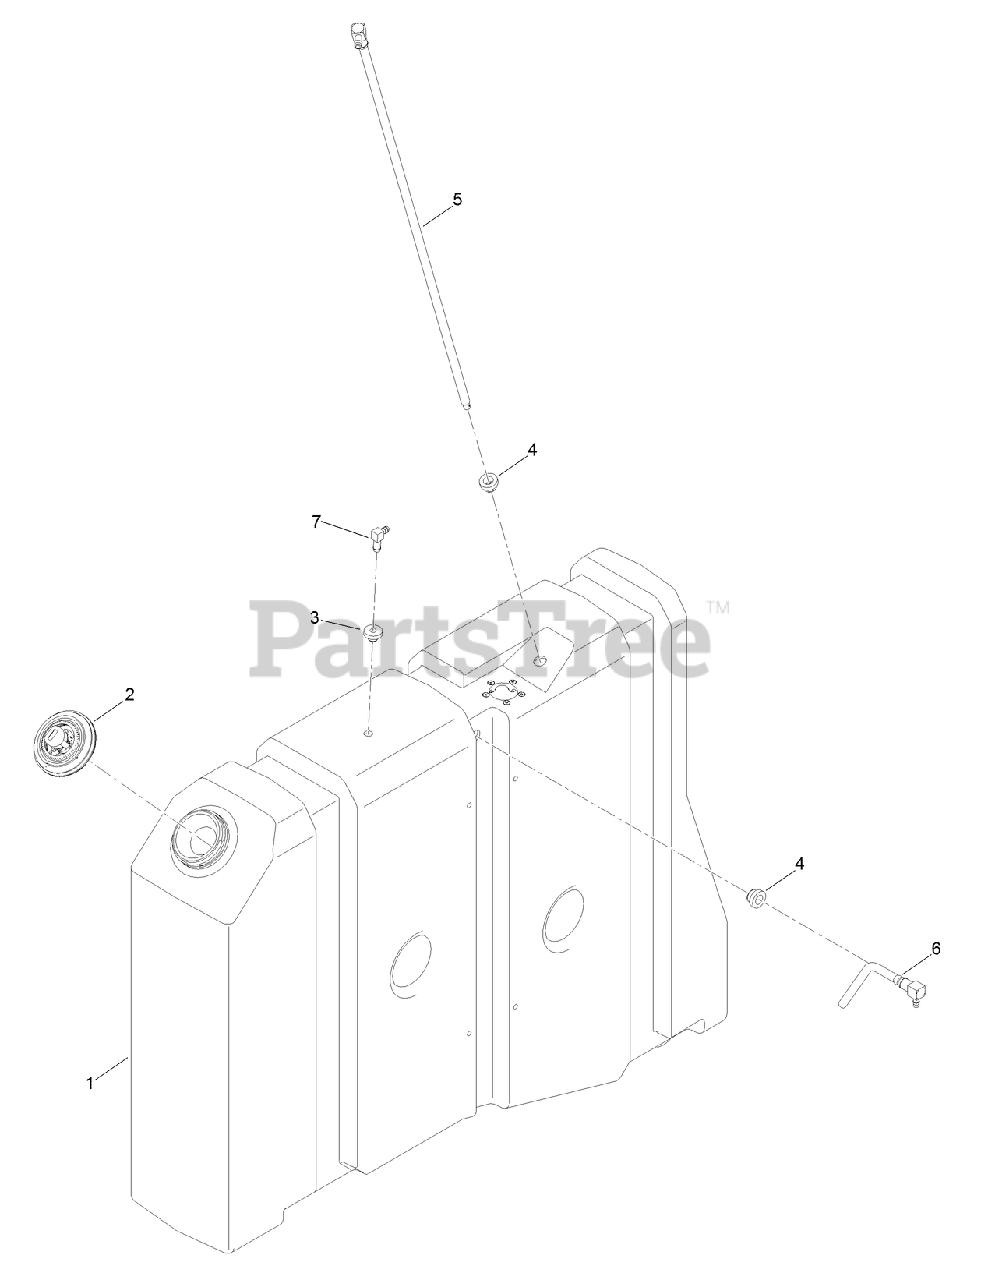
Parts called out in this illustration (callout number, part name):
1	TANK-FUEL
2	CAP-FUEL, LOCKING
3	BUSHING
5	PIPE-STAND, FUEL
6	PIPE-STAND, RETURN
7	FITTING-ELBOW, 90 DEG
